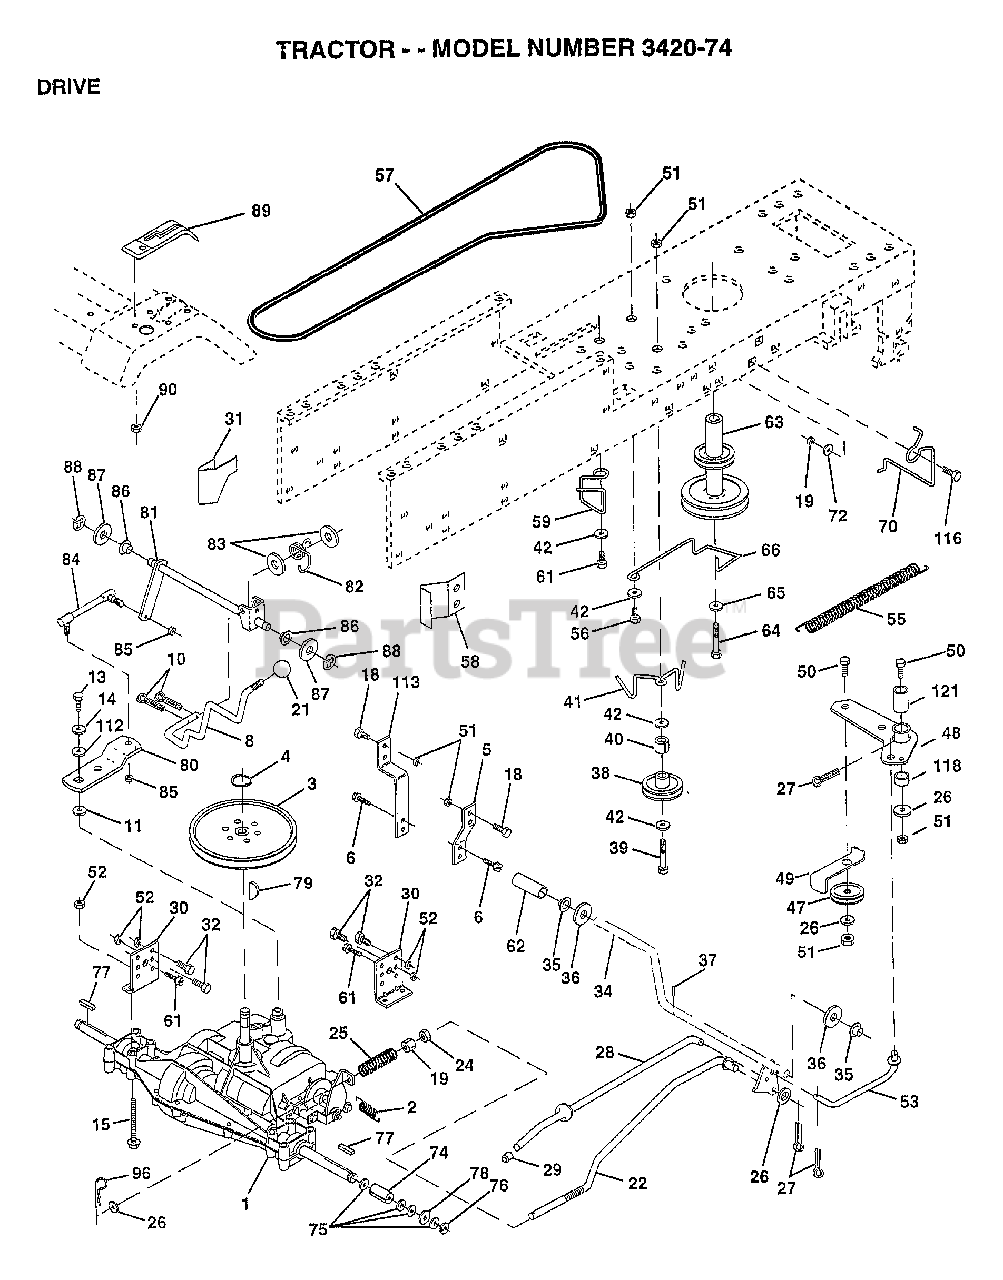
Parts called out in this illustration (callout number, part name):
1	TRANSAXLE, PEERLESS
2	SPRING.BRAKE.RETU
3	PULLEY TRANS
5	STRAP TORQUE
6	SCREW
8	ROD SHIFT FEND LT
10	PIN COTTER 1/8
11	WASH-SHFT PLT LT
12	WASHER
13	BOLT.1/4-28.W/PAT
14	LOCKWASHER
15	BOLT.HX.FLG.5/16
18	BOLT
19	NUT
21	KNOB T (1/2-HOLE)
22	BRAKE ROD
24	NUT
25	SPRING ROD LT
26	WASHER
27	COTTER PIN
28	ROD.BRAKE.PARK.LT
29	PLUNGER CAP T
30	TRANSAXLE MTG BKT
31	"KEEPER,BELT LH T"
32	BOLT
34	SHAFT ASM-PEDAL F
35	NYLON BEARING
36	WASHER LT
38	PULLEY.IDLER.FLAT
39	BOLT
40	SPACER T
42	WASHER
48	BELLCRANK ASM
49	RETAIN BELT
53	"LINK, CLUTCH T"
55	"SPRING, RETURN LT"
58	"KEEPER,BELT RH T"
59	KEEPER BELT CNTSP
61	SCREW
62	PEDAL COVER T
63	PULLEY.ENGINE
64	BOLT
65	LOCKWASHER
66	KEEPER-BELT
70	KEEPER BELT ENG
72	WASHER
74	SPACER AXLE
75	WASHER
76	E-RING LT
77	SQUARE KEY
78	WASHER
80	"ARM.SHIFT.20""TIRE"
81	SHAFT.CROS.P930.
82	"SPRING,TORSION"
83	WASHER
84	"ROD.TIE.20""P930LT"
85	NUT.CNT.LOCK.1/4
86	BUSHING
87	WASHER D
88	KLIP RING
90	NUT
96	RETAINER M
112	WASHER LT
113	"STRAP,TORQUE"
116	BOLT RDHD 3/8-16
118	SPACER-BELLCRANK
121	NYLINER-CLUTCHING
